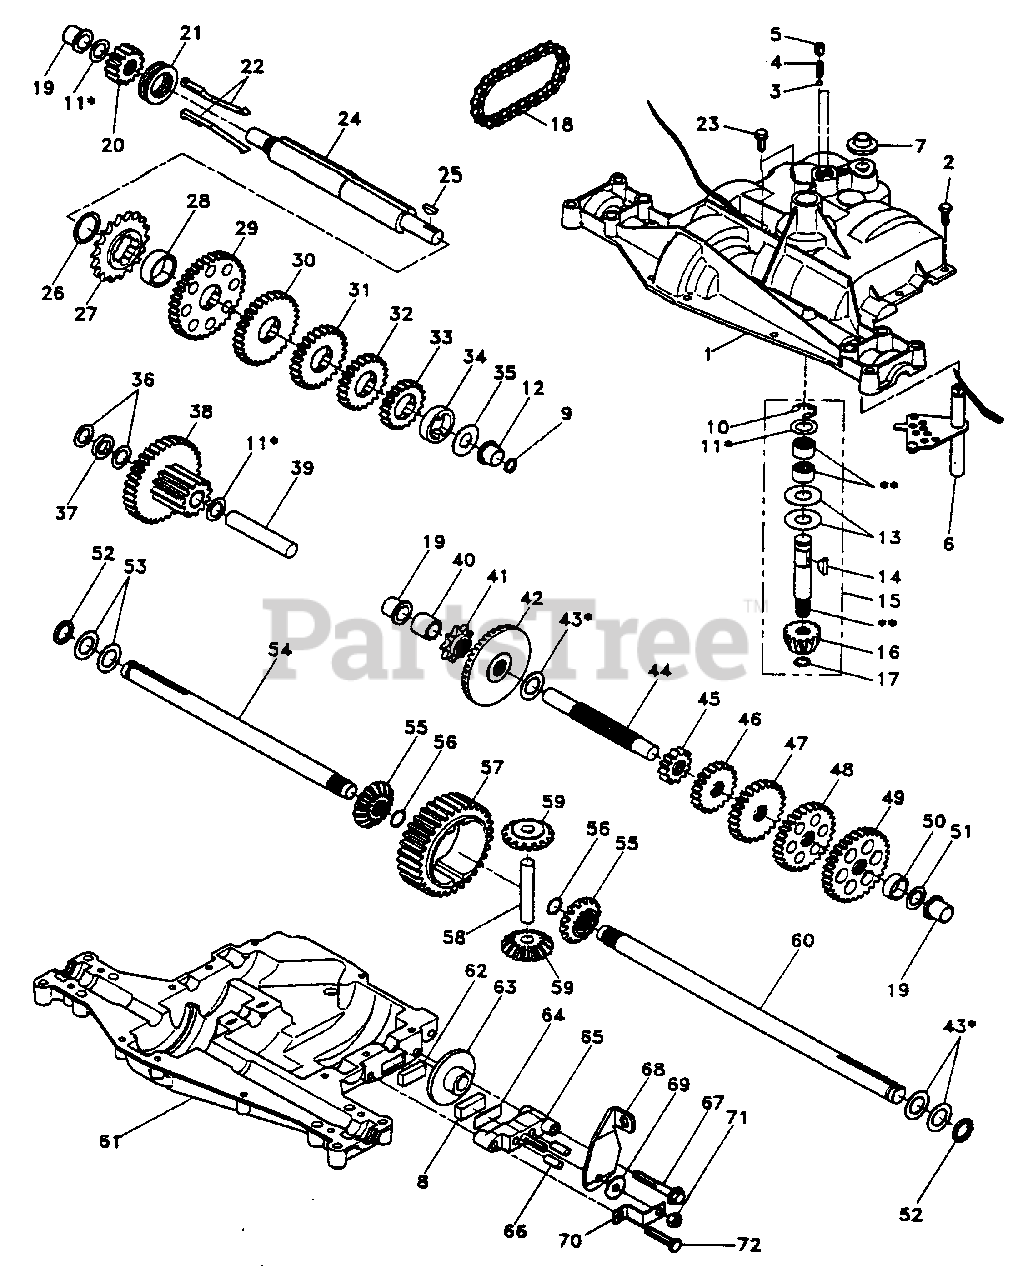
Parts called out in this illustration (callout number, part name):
1	Housing, Upper (AYP part number)
2	Screw, Self-Tapping, Large 1/4-20 x .734 (AYP part number)
3	Ball, Detent (AYP part number)
4	Spring, Detent (AYP part number)
5	Screw, Set (AYP part number)
6	Kit, Shifter Assembly (AYP part number)
7	Boot, Shifter (AYP part number)
8	Puck, Friction (AYP part number)
9	Seal, Oil (AYP part number)
10	Ring, Retaining (AYP part number)
11	Assembly, Kit, Shim .625 Shaft (AYP part number)
12	Bearing, Flange (AYP part number)
13	Washer, Plain .632 x 1.38 x .046 (AYP part number)
14	Key, Woodruff, #9 (AYP part number)
15	Assembly, Kit, Input Shaft (AYP part number)
16	Pinion, Bevel, 14 Teeth (AYP part number)
17	Ring, Retaining (AYP part number)
18	Chain, 24 Pitches (AYP part number)
19	Bearing, Flange (AYP part number)
20	Gear, Spur, 14 Teeth (AYP part number)
21	Collar, Clutch (AYP part number)
22	Assembly, Kit, Clutch Keys (AYP part number)
23	Screw, Self-Tapping, with Sealer (AYP part number)
24	Shaft, Intermediate (AYP part number)
25	Key, Woodruff, #61 (AYP part number)
26	Ring, Retaining (AYP part number)
27	Sprocket, 18 Teeth (AYP part number)
28	Spacer (AYP part number)
29	Gear, Spur, 37 Teeth (AYP part number)
30	Gear, Spur, 30 Teeth (AYP part number)
31	Gear, Spur, 25 Teeth (AYP part number)
32	Gear, Spur, 22 Teeth (AYP part number)
33	Gear, Spur, 19 Teeth (AYP part number)
34	Spacer 1.133 x 1.50 x .375 (AYP part number)
35	Washer, Plain .640 x 1.37 x .061 (AYP part number)
36	Washer, Plain .632 x 1.00 x .026 (AYP part number)
37	Spacer .630 x 1.00 x .169 (AYP part number)
38	Ass'y, Gear, Combination of 12 & 35 Teeth (AYP part number)
39	Shaft, Idler (AYP part number)
40	Spacer .635 x .875 x .755 (AYP part number)
41	Sprocket, 9 Teeth (AYP part number)
42	Gear, Bevel, 42 Teeth (AYP part number)
43	Assembly, Kit, Shim .750 Shaft (AYP part number)
44	Shaft, Drive (AYP part number)
45	Gear, Spur, 12 Teeth (AYP part number)
46	Gear, Spur, 20 Teeth (AYP part number)
47	Gear, Spur, 25 Teeth (AYP part number)
48	Gear, Spur, 28 Teeth (AYP part number)
49	Gear, Spur, 31 Teeth (AYP part number)
50	Spacer .781 x 1.00 x .375 (AYP part number)
51	Washer, Plain .632 x 1.00 x .060 (AYP part number)
52	Washer, Neoprene (AYP part number)
53	Washer, Plain .758 x 1.25 x .031 (AYP part number)
54	Axle, L.H. (AYP part number)
55	Gear, Miter, 15 Teeth (AYP part number)
56	Ring, Retaining (AYP part number)
57	Gear, Spur, 32 Teeth (AYP part number)
58	Shaft, Cross (AYP part number)
59	Gear, Miter, 15 Teeth (AYP part number)
60	Axle, R.H. (AYP part number)
61	Housing, Lower (AYP part number)
62	Puck, Friction (AYP part number)
63	Disc, Brake (AYP part number)
64	Spacer (AYP part number)
65	Jaw, Brake (AYP part number)
66	Pin, Dowel (AYP part number)
67	Screw, Self-Tapping, Large 5/16-18 x 2.25 (AYP part number)
68	Lever, Actuating (AYP part number)
69	Washer, Plain .321 x 1.00 x .055 (AYP part number)
70	Bracket, Anti-Rotation (AYP part number)
71	Locknut 5/16-24 (AYP part number)
72	Screw, Self-Tapping, Large 5/16-18 x 1.44 (AYP part number)
73	Grease (AYP part number)
